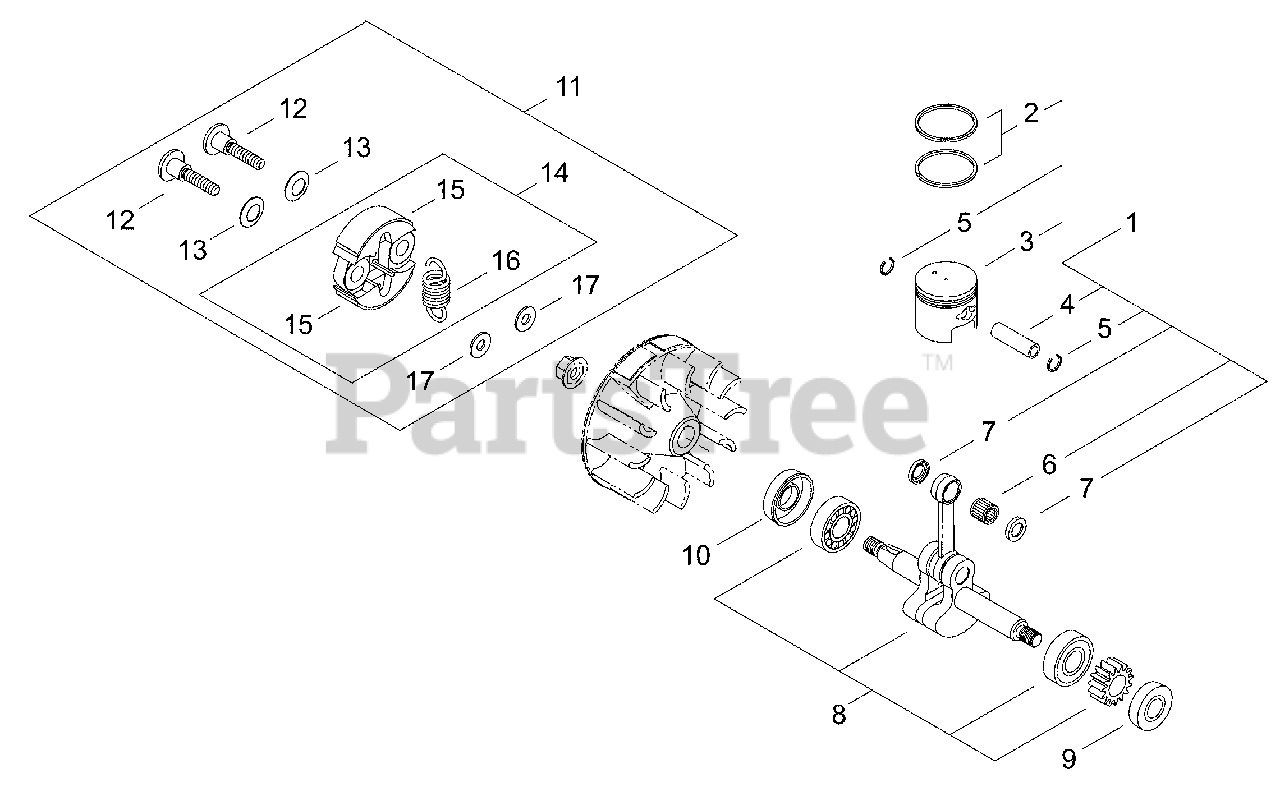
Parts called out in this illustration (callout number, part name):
1	PISTON KIT
2	RING, PISTON
3	PISTON
4	PIN, PISTON
5	RING, RETAINING
6	BEARING, NEEDLE
7	SPACER - 9
8	CRANKSHAFT ASSY
9	SEAL, OIL - 12
10	SEAL, OIL - 12
11	CLUTCH SHOE SET
12	BOLT, CLUTCH
13	WASHER - SPRING
14	CLUTCH ASSY
15	SHOE, CLUTCH
16	SPRING, CLUTCH
17	WASHER - 6
